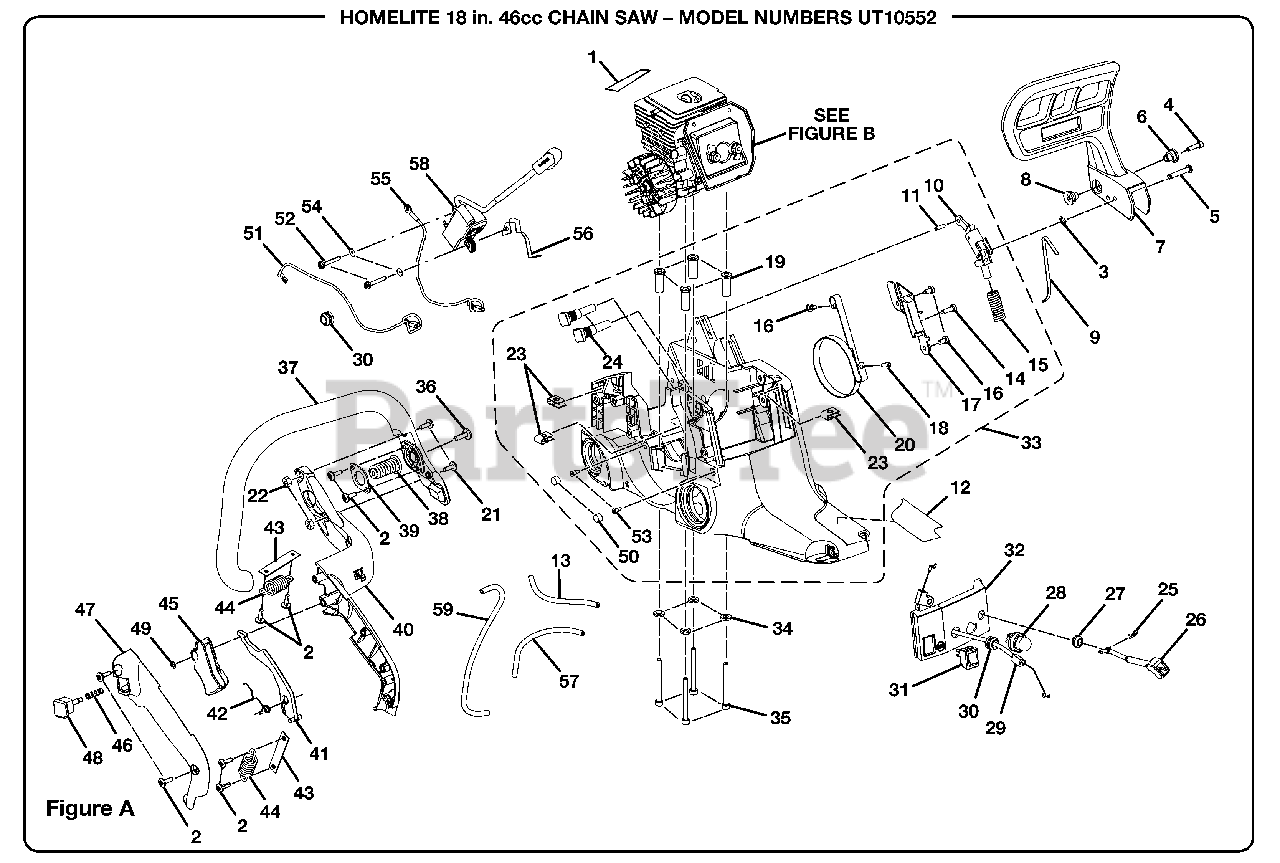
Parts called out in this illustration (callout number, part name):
1	Heat Reflector Tape
2	Screw (10-14 X 5/8 in. Torx Pan Hd.)
3	Retaining Ring
4	Screw (8-32 X 5/8 in. Hex Soc. Hd.)
5	Handguard Lever Pin
6	Pivot (Right Hand)
7	Handguard
8	Pivot (Left Hand)
10	Chain Brake Link Assembly
11	Roll Pin (Small)
12	On-board Label
13	Rubber Tubing (95 mm)
14	Screw (8-16 X 17 mm)
15	Spring
16	Screw (8-16 X 0.32 Pan Hd.)
17	Brake Band Cover
18	Roll Pin (Big)
19	Spacer Insert
20	Chain Brake Band Kit
21	Screw (10-24 X 19.5 mm)
22	Lock Nut (10-24)
23	Speed Nut ("U"-type)
24	Guide Bar Bolt
25	Spring Clip
26	Choke Rod
28	Primer Assembly
29	Throttle Cable
30	Split Grommet
31	Switch
32	Control Panel
33	Chassis Assembly
35	Screw (10-24 X 2 in. Soc. Cap Hd.)
36	Screw (10-24 X 5/8 in. Torx Hd.)
37	Front Handle
38	Upper Isolator Spring
39	Isolator Plate
40	Handle Support
41	Lockout Throttle
42	Torsion Spring
43	Isolator Limiter
44	Isolator Spring
47	Handle Cover
48	Throttle Lock Pin
49	Retaining Ring
51	Lead, Ignition Wire
52	Screw (9-15 x 1 in.)
53	Duck Bill Valve
55	Lead,ground Wire
56	Lead,ground Wire
57	Rubber Tubing (120 mm)
58	Ignition Module
59	Rubber Tubing (222 mm)
